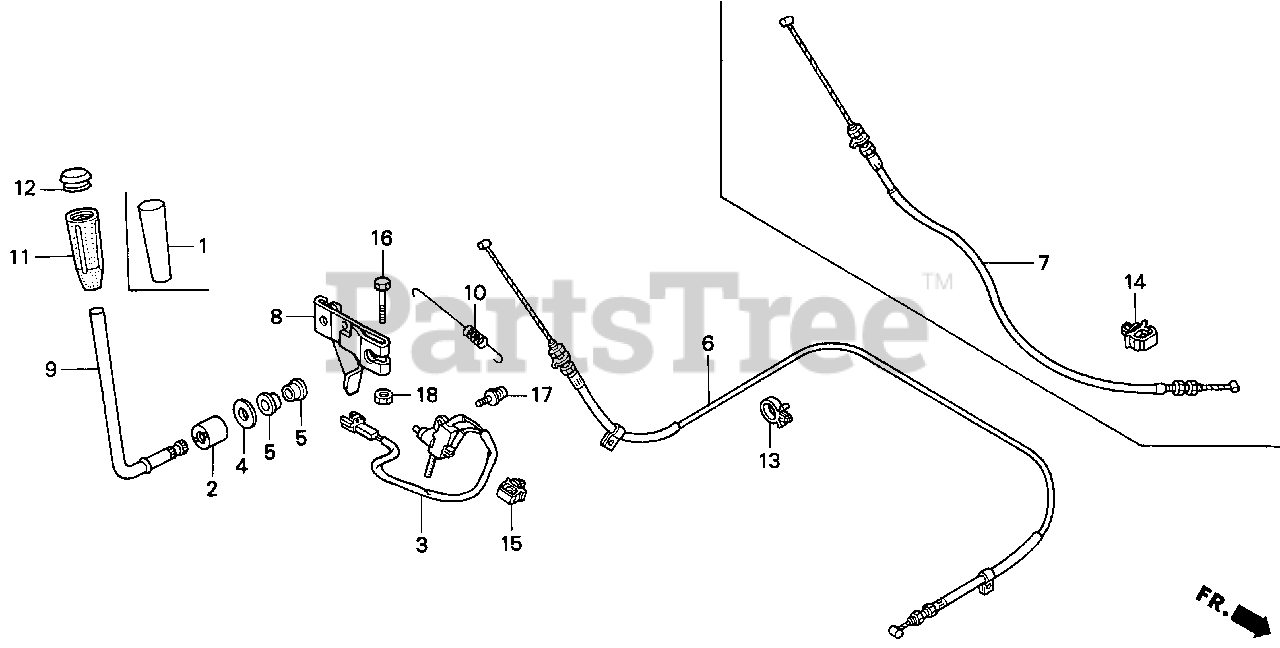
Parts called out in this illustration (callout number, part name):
1	GRIP, P.T.O. CLUTCH LEVER *Y121* (YELLOW)
3	SWITCH ASSY., P.T.O. CLUTCH
4	PLATE, STOPPER
5	BUSH A, CHANGE LEVER
6	CABLE, P.T.O. CLUTCH
6	CABLE, P.T.O.
8	ARM, P.T.O. CLUTCH LEVER
9	LEVER, P.T.O. CLUTCH
10	SPRING, P.T.O. CLUTCH
13	CLIP, WIRE HARNESS
15	CLIP, WIRE HARNESS
16	BOLT, HEX. (6X32)
17	SCREW-WASHER (4X12)
18	NUT, HEX. (6MM)
